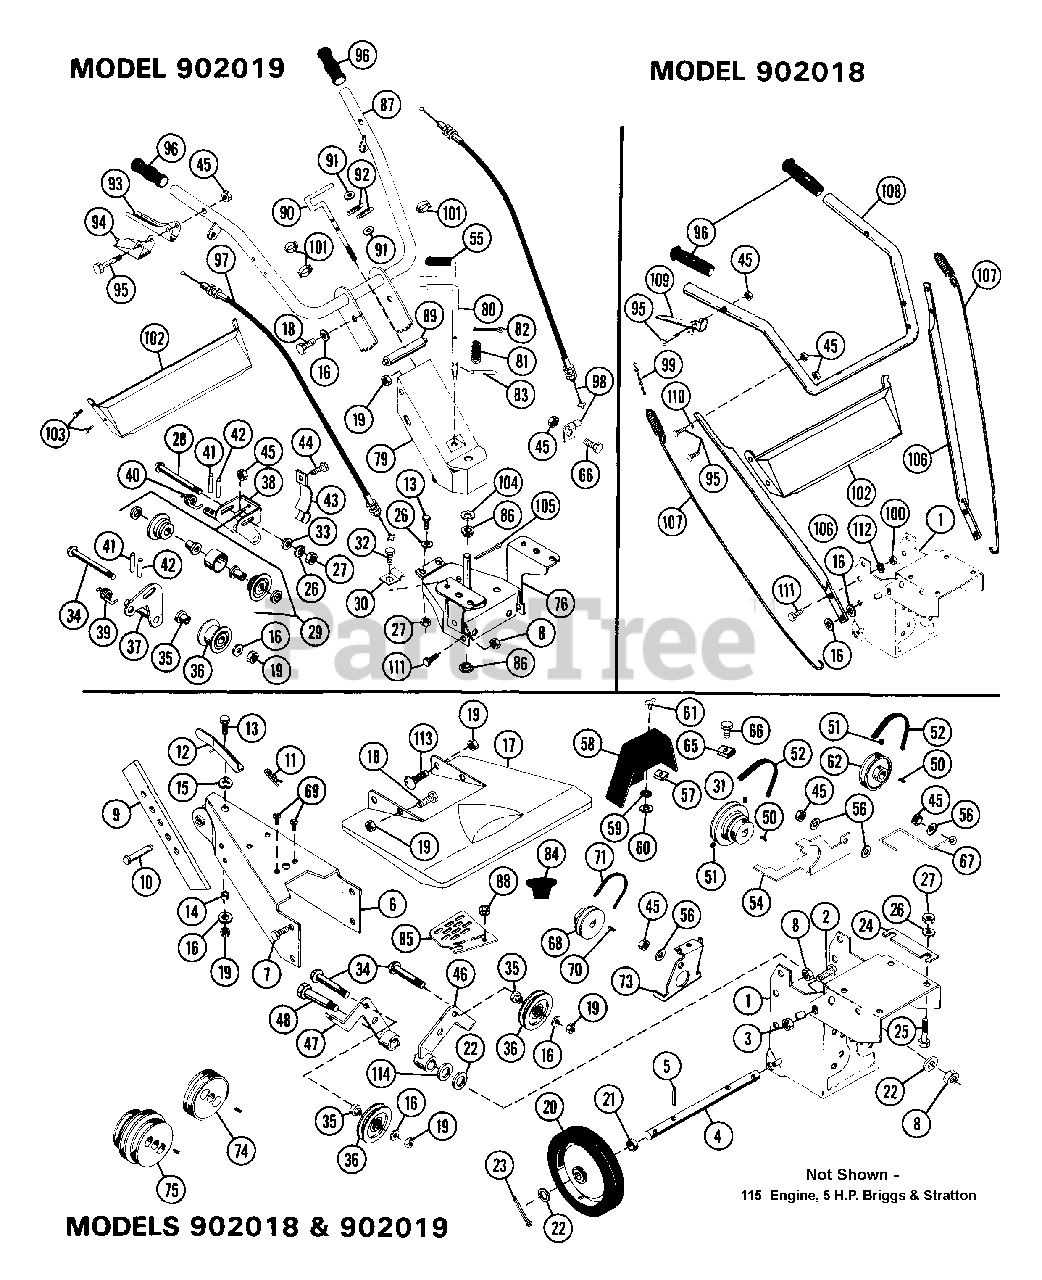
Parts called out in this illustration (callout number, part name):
1	FRAME
2	BLT-HEX .38-16X2.50 PL GR5
2	BLT-HEX .38-16X.75 PL GR5
3	NUT-LK TOP .375-16 GR C YWZC
4	AXLE ROD
5	PIN-ROLL .125X1.38
6	DEPTH STICK HOLDER
7	BLT-HEX .38-16X.75 PL GR2
8	NUT-LK-CTR .375-16 GR A PL
9	DEPTH STICK
10	CLEVIS PIN .437/.431X1.50 YWZC
11	PIN-HAIR INT .12X2.75
12	RETAINER CLIP
13	BLT-HEX .31-18X.75 PL GR2
14	SPACER BUSHING .5 X .32 X .21
15	WAVE WASHER .515 X 1.00 X .125
16	WSHR-FL-STL .38X.875X.083 PL
17	TINE HOOD
18	BLT-HEX .31-18X.63 PL GR 2
19	NUT-LK .312-18 GR A PL
21	SPACER .76 X .51 X .56
22	WSHR-FL-STL .531X1.062X.095 PL
23	PIN-COTR .12 X 1.25 PL
24	SHIM
25	BLT-HEX .31-18X1.75 PL GR2
26	WSHR-LK .312X.097 PL HVY
27	NUT-HEX .312-18
28	BLT-HEX .31-18X2.75 PL GR2
29	IDLER ASSEMBLY
30	CABLE CLAMP
31	ENGINE SHEAVE
32	SCR-TAP 10-24X.375 HWH PL TR
33	WSHR-FL-STL .323X.625X.062 PL
34	BLT-RDHDSQNK .31-18X1.25 SHTPL
35	SPCR, BRG .315X.50X.688X.281
36	IDLER
37	REVERSE IDLER ARM
38	FORWARD IDLER BRACKET
39	SG-TORS .072X.52X.75
40	SG-TORS .072X.50X.520
41	PIN-ROLL .188X1.50
42	PIN-ROLL .125X.75
43	BRACKET
44	BLT-HEX .25-20X.63 PL GR2
45	NUT-LK-CTR .250-20 PL
46	IDLER ARM FWD
47	IDLER ARM REV.
48	WHEEL SHOULDER BOLT
50	KEY-SQ .188X1.0X.188 SAE 8630
51	SET SCREW
52	V-BELT, 4L-WRAPPED
54	FWD BELT FINGER
55	GRIP
56	WSHR-FL-STL.281X.62X.065 PL
57	NUT-SPEED 1/4 TURN SOUTHCO
58	BELT COVER
59	NUT-RETNR
60	WSHR-FL-STL .250X.562X.049 PL
61	SCR-WING .25 TURN SOUTHCO
62	ENGINE SHEAVE
65	NUT-SPEED U-TYPE .250-20
66	BLT-HEX .25-20X.50 PL GR2
67	FWD BELT FINGER
68	REVERSE SHEAVE
69	BLT-SERRDHD SL .31-18X.75 YZ
70	KEY-WDRF .125X.625X.250 SAE5
71	V-BELT, 3L-WRAPPED
73	REVERSE BELT FINGER
74	PLY-DBLV 5.50 X.75 W/KEY SALEM
75	PLY-TRPY 5.50 X .75 W/KEY
76	SWING HANDLE BRACKET
79	HANDLE BAR SWIVEL
80	SWIVEL PIN
81	SG-COMP .062X.64X3.40 WLD 10
82	PIN-COTR .09X1.0 PL
83	PIN-ROLL .125X1.38
84	KNOB W/10-24 TAPPED METAL INSE
85	MUFFLER SHIELD
86	BSHG-FLG .750X1.000X.625X1.250
87	HANDLEBAR
88	NUT-FLG. .312-18 PL
89	HANDLE LOCK
90	HANDLE
91	WSHR-FL-STL .438X1.0X.083 PL
92	PIN-GRV .125X1.00 TP E
93	HANDLE
94	HANDLE ADAPTER
95	BLT-HEX .25-20X1.50 PL GR5
96	GRIP
97	CLUTCH CABLE
98	CLUTCH CABLE
99	CLUTCH CHAIN
100	NUT-HEX .375-16
101	CLAMP
102	HANDLEBAR PANEL
103	BLT-SCRHFWH .25-20X.62 PL
104	WSHR-FL-STL .755X1.375X.125 PL
105	PIN-COTR .18X1.50 PL
106	LOWER HANDLE BAR
107	SG-TENS .080X.25X31.6 WLD 35
108	HANDLEBAR
109	CLUTCH HANDLE
110	WSHR-FL-STL .268X.562X.046 PL
111	BLT-HEX .38-16X1.00 PL
112	WSHR-LK .375X.115 HVY PL
113	BLT-RDHDSQSHNK .31-18X.50 YZ
114	WSHR-FL-STL .520X.827X.062 YZ
115	ENGINE, 5 H.P. BRIGGS & STRATTON
